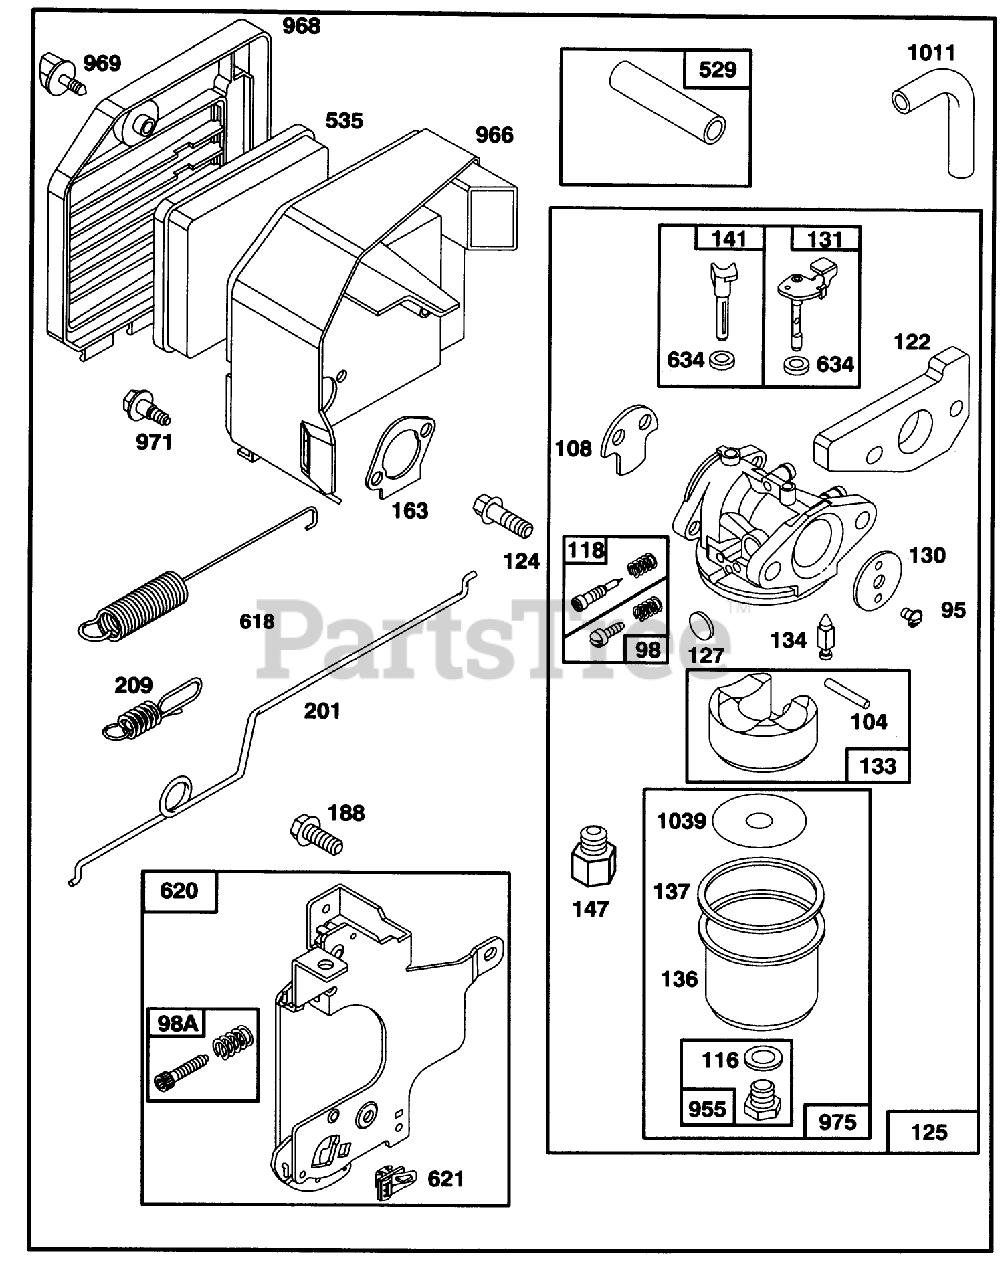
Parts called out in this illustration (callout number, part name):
98	IDLE ADJUSTING SCREW
98A	SPEED ADJUST. SCREW ASM
116	SEALING GASKET
118	VALVE KIT - NEEDLE
122	ADAPTER ASSEMBLY
124	HEX HEAD SCREW
130	THROTTLE VALVE
133	FLOAT-CARBURETOR
134	VALVE-FLOAT
137	FLOAT BOWL GASKET
147	JET ADAPTER
163	AIR CLEANER GASKET
188	SCREW - SEM
201	GOVERNOR LINK
209	GOVERNOR SPRING
529	BREATHER TUBE
535	FILTER ELEMENT
618	RETURN SPRING
621	STOP SWITCH
966	AIR CLEANER BASE
969	AIR CLEANER SCREW
971	AIR CLEANER SCREW
1011	VENT TUBE
1039	FLOAT LIMITER
